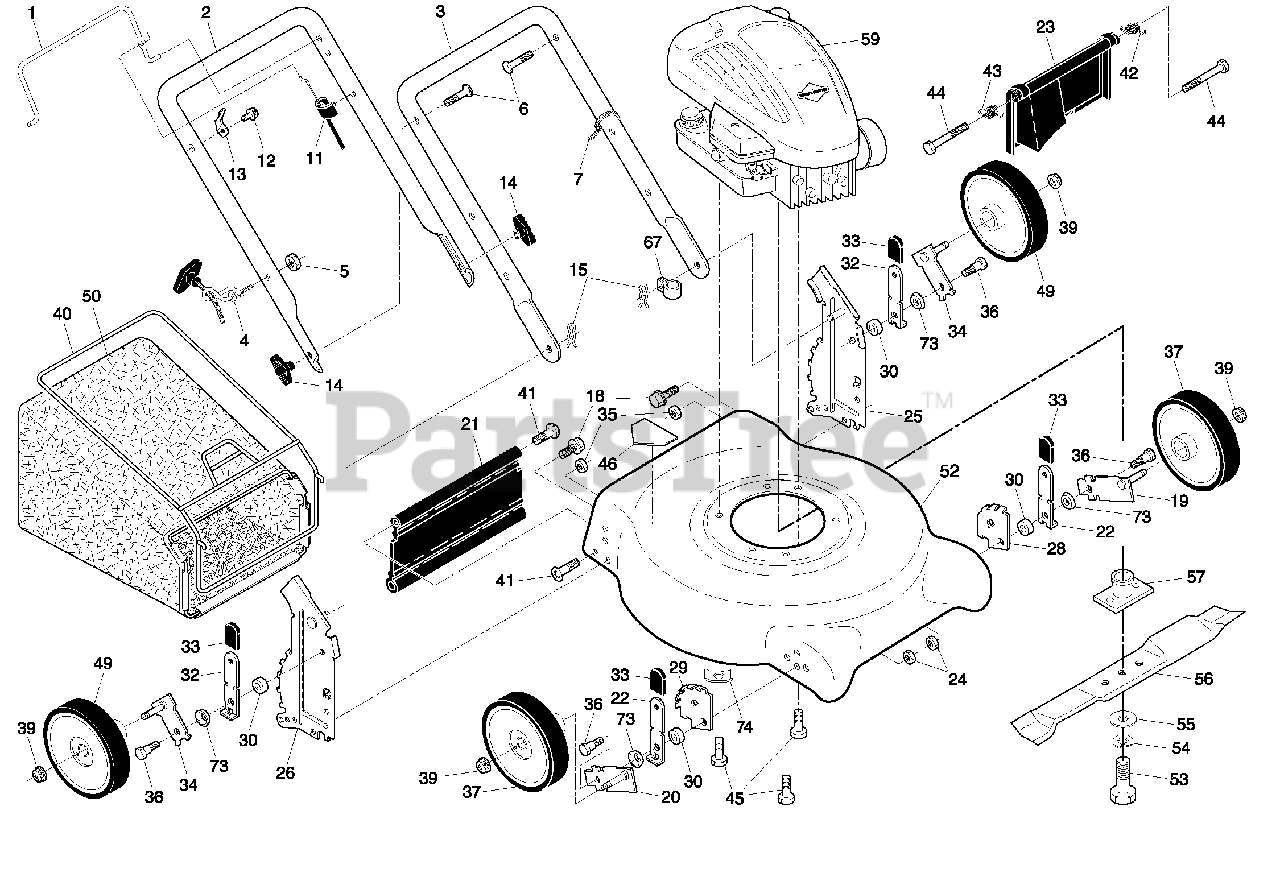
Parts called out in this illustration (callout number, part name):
1	Control Bar
2	Upper Handle
3	Lower Handle
4	Rope Guide
6	Handle Bolt
7	Wire Tie
11	Engine Zone Control Cable
12	Hex Washer Head Screw
13	Up-Stop Bracket
14	Handle Knob
15	Hairpin Cotter
18	Screw 1/4-20 x 3/8
19	Axle Arm Assembly, Front, LH
20	Axle Arm Assembly, Front, RH
21	Rear Skirt
22	Selector Spring, Front
23	Rear Door Assembly
24	Locknut, Hex
25	Handle Bracket Assembly, LH
26	Handle Bracket Assembly, RH
28	Wheel Adjusting Bracket, Front, LH
29	Wheel Adjusting Bracket, Front, RH
30	Spacer
32	Selector Spring, Rear
33	Selector Knob
34	Axle Arm Assembly, Rear
35	Locknut 5/16-18
36	Shoulder Bolt 5/16-18
37	Wheel & Tire Assembly, Front
39	Locknut, Hex, Flanged
40	Frame, Grass Bag
41	Hinge Screw
42	Spring, Rear Door, LH
43	Spring, Rear Door, RH
44	Bolt, Rear Skirt
45	Hex Head Thread Rolling Screw 3/8-16 x 1
46	Danger Decal
49	Wheel & Tire Assembly, Rear
50	Grass Bag
52	Housing Assembly
53	Hex Head Screw 3/8-24 x 1-3/8 Grade 8
54	Helical Lockwasher
55	Hardened Washer
56	21" Blade
57	Blade Adapter
67	Clip, Cable
73	Washer, Flat
74	Washer, Special, Engine
74	Operator's Manual, English
74	Operator's Manual, Spanish
74	Repair Parts Manual
